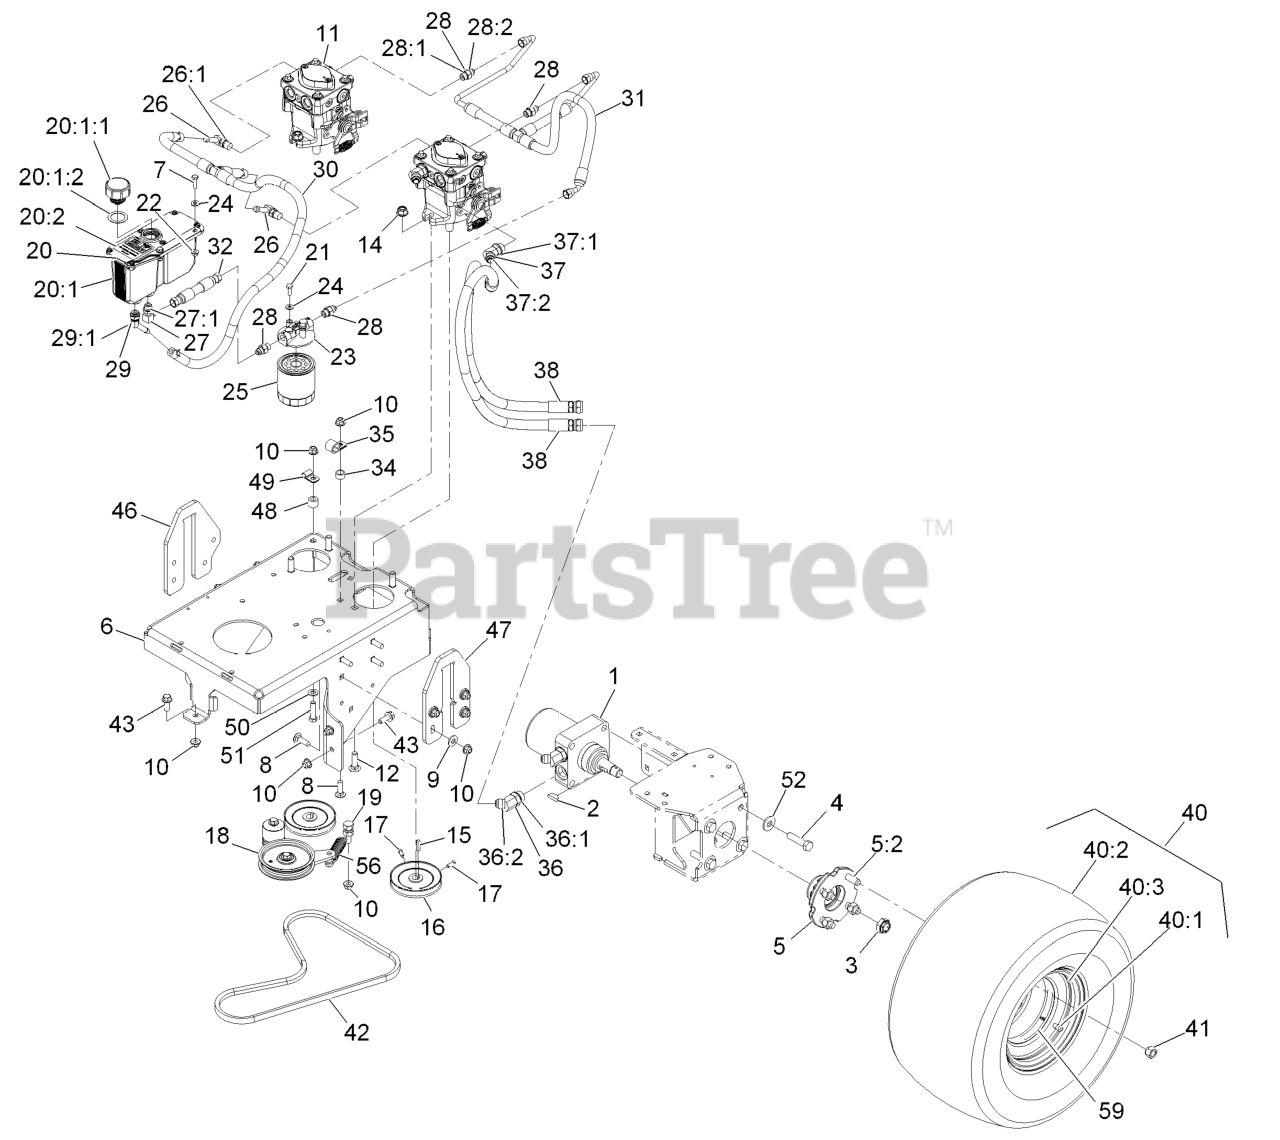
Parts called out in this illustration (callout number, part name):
1	MOTOR-WHEEL
2	KEY-WOODRUFF
3	NUT-LOCK
4	SCREW-HH
5	WHEEL HUB ASM
5:2	STUD-TYPE, DRIVE
7	SCREW-HH
8	BOLT-CARR
9	WASHER-BELLEVILLE
10	NUT-HF, NI
11	PUMP - HYDRAULIC
12	SCREW-HH
14	NUT-HF, NI
16	PULLEY-PUMP
17	SCREW-SET
18	PUMP IDLER ASM
20	RESERVOIR ASM
20:1	Reservoir-Hyd
20:1:1	Cap-Reservoir, HYD
20:1:2	GASKET-CAP
20:2	DECAL-HYDRAULIC TANK
21	SCREW-HH
22	NUT-HHF
23	HEAD-FILTER
24	WASHER-FLAT
25	FILTER-25 MICRON, BI-DIRE
26	FITTING-ELBOW, 90
26:1	O-RING
27	FITTING-ELBOW, 90 DEG
28	FITTING-STRAIGHT
29	FITTING-BARBED, 45 DEG
29:1	O-RING
30	TANK HOSE ASM
31	HOSE ASSEMBLY - CHARGE
32	HYD HOSE ASM
34	SPACER-WHEEL
35	CLIP-LOOM
36	FITTING-HYD, 45 DEG
37	FITTING-HYD, 45 DEG
40	WHEEL ASM
40:1	Stem-Valve
40:3	RIM-8 INCH
41	NUT-LUG
42	BELT-V, LOWER PTO
43	SCREW-HHF 3/8-16 X 1
46	PLATE-LIFT, RH
47	PLATE, LIFT LH
48	SPACER-PIVOT
49	CLIP-TUBE
50	WASHER-FLAT
51	SCREW-HH
52	WASHER-SPRING
56	SPRING-EXTENSION
